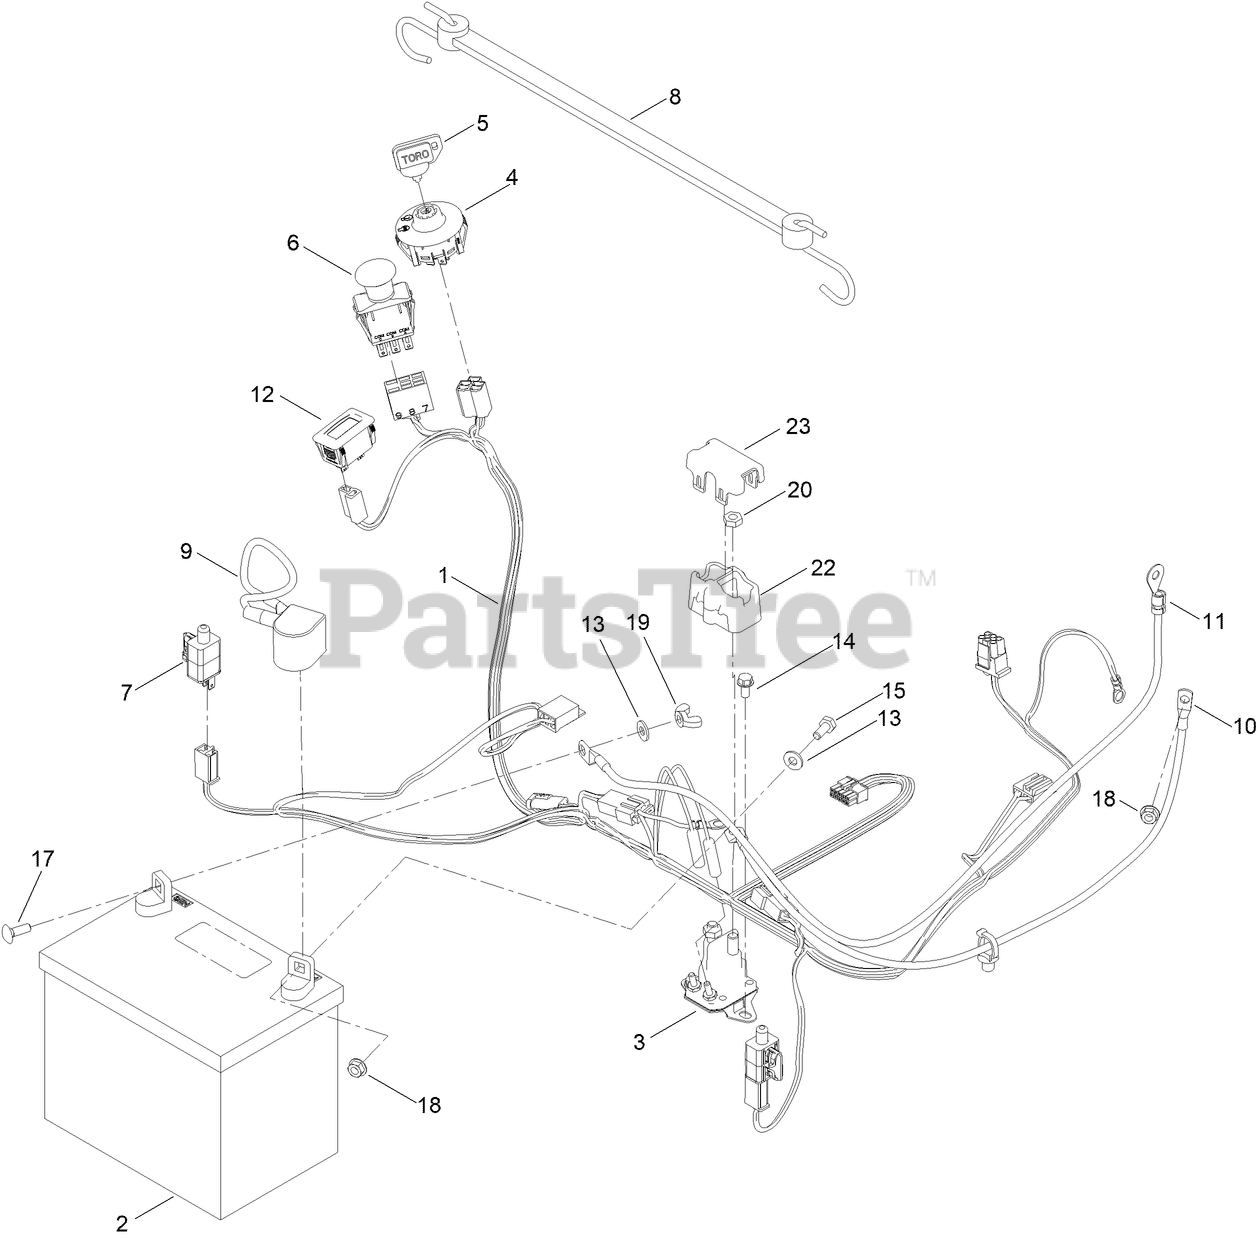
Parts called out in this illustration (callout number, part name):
1	HARNESS-WIRE
2	BATTERY
3	SOLENOID
4	SWITCH-IGNITION
5	KEY-IGNITION
6	SWITCH-PTO
7	SWITCH
8	STRAP-RUBBER
9	CABLE-BATTERY, POS
10	CABLE-BATTERY, RED (8 GAUGE)
11	CABLE-BATTERY, BLACK
12	HOURMETER
13	WASHER-FLAT
14	SCREW-HWH
15	SCREW-HH
17	BOLT-CARR
18	NUT-HF
19	NUT-WING
20	NUT-JAM
22	COVER-SOLENOID
23	CAP-SOLENOID
